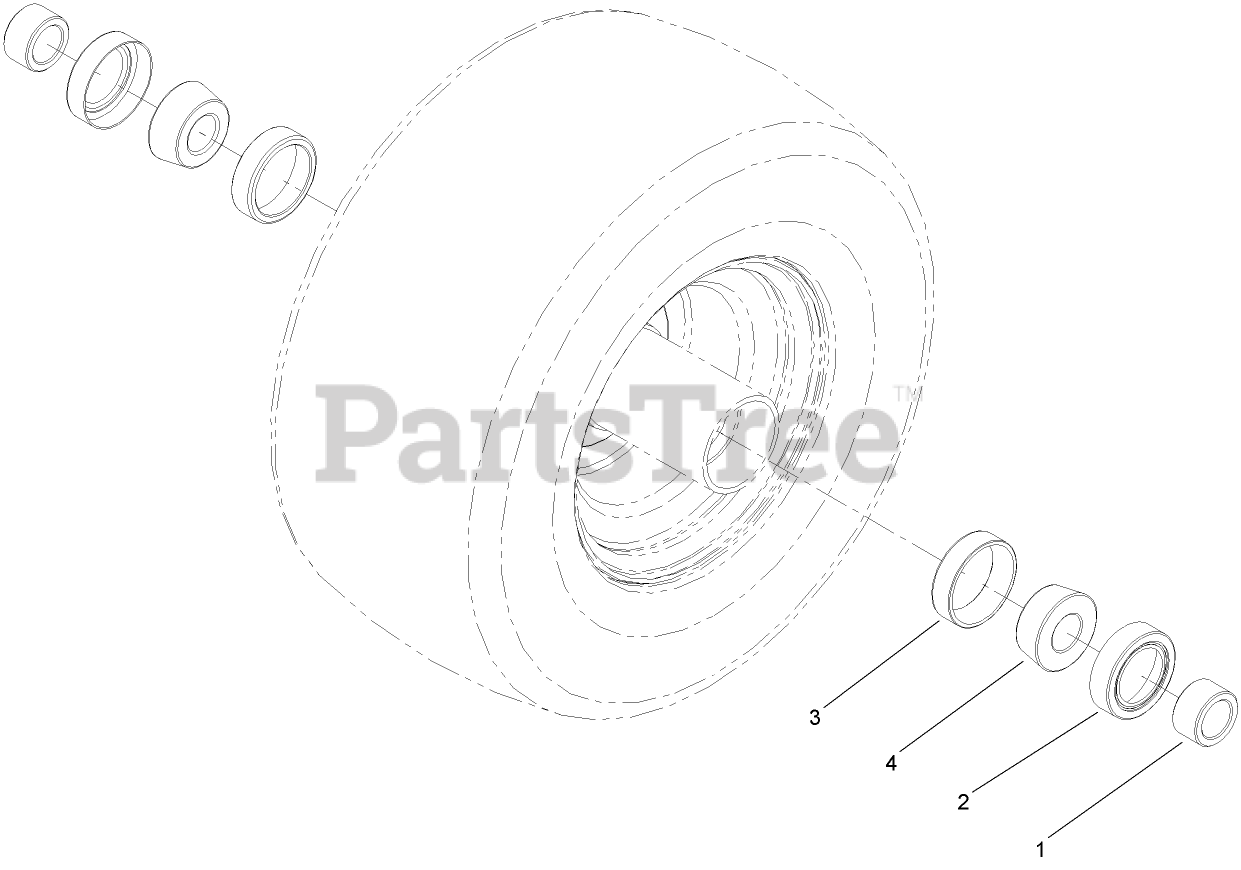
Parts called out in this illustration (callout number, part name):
1	SPACER-BEARING
2	SEAL-BEARING
3	BEARING-CUP
4	BEARING-CONE, TAPER
